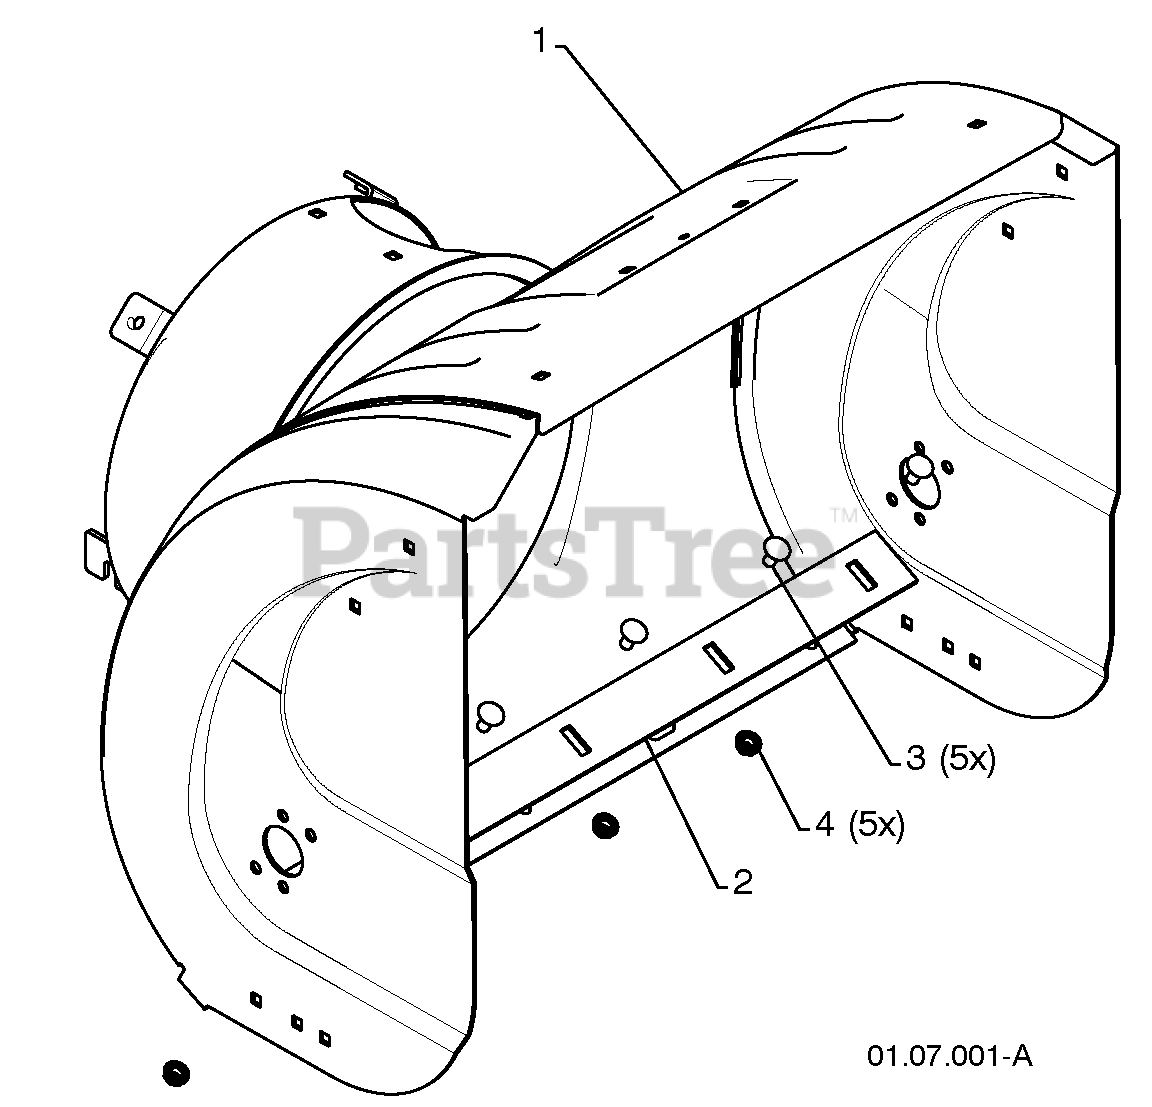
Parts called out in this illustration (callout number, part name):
1	AUGER HOUSING
2	SCRAPPER BAR
3	CARRIAGE BOLT 5/16-18 X .625
4	NUT 5/16-18
